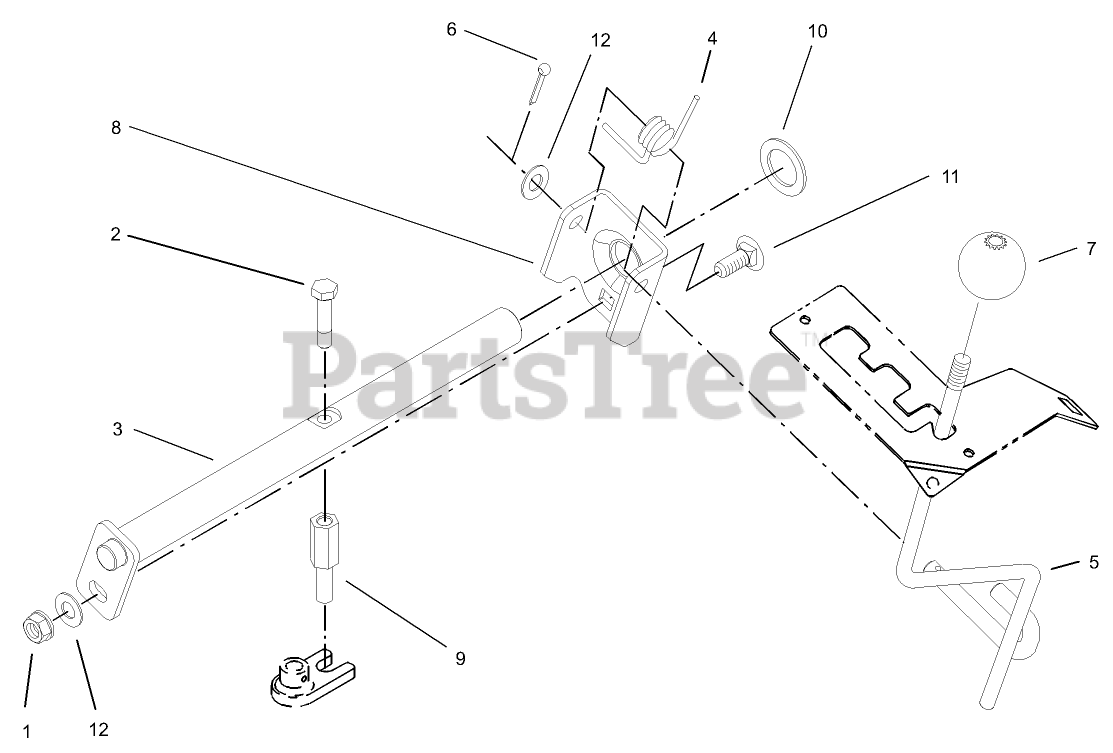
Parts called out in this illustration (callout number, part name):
1	NUT-LOCK, NI
2	SCREW-THREAD LOCKING
3	SHIFT ROD ASM
4	SPRING-TORSION
5	LEVER-SHIFT
6	PIN-COTTER
8	BRACKET-PIVOT
9	ROD-PIVOT, SHIFT
10	SPACER
11	SCREW-CARR
12	WASHER-FLAT
